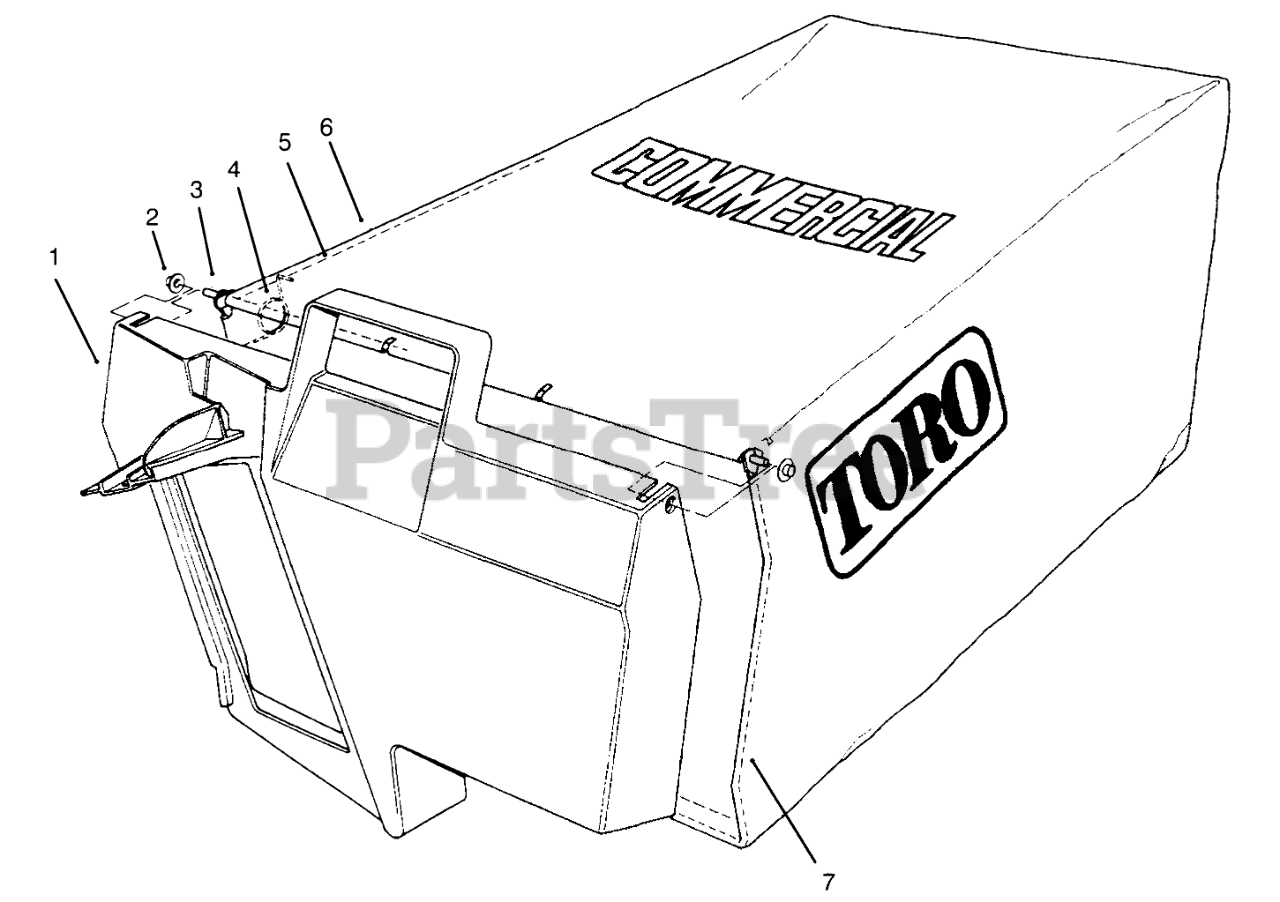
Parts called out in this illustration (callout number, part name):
1	DOOR-BAG, GRASS
2	NUT-PUSH
3	HINGE-DOOR, BAG
4	SPRING
5	FRAME-BAG, UPPER
6	Bag
7	FRAME-BAG
